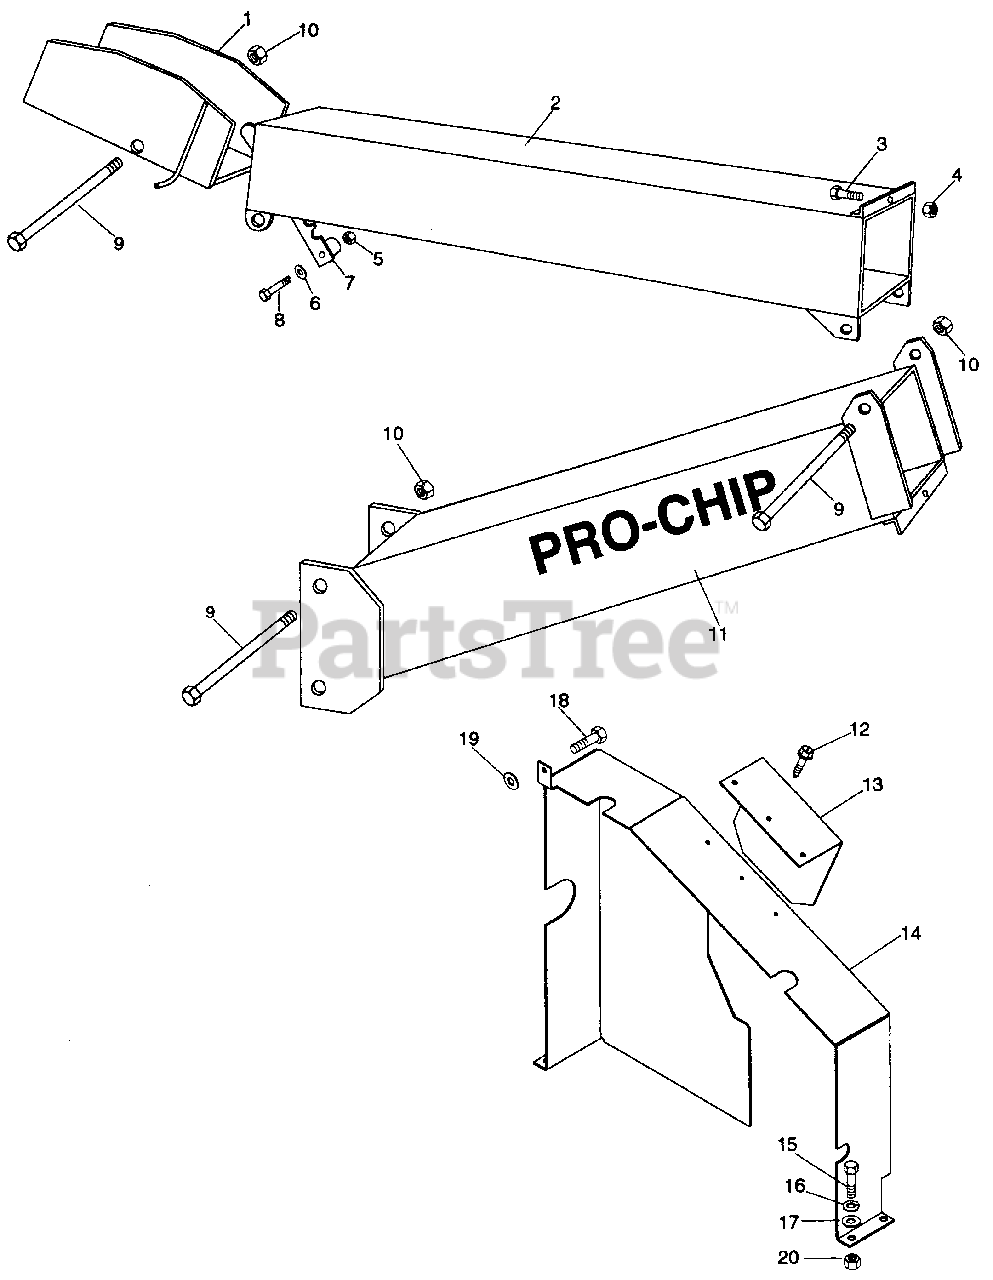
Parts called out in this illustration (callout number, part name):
1	CAP
2	CHUTE UPPER
3	BLT-HEX .31-18X.75 PL GR 5
4	NUT-LK-NYL .312-18 PL
5	NUT-LK TOP .375-16 GR C PL
6	WSHR-FL-STL .438X1.0X.083 PL
7	LOCK BAR
8	BLT-HEX .38-16X2.00 PL GR 5
9	BLT-HEX .38-16X6.00 PL GR 5
10	NUT-LK TOP .375-16 GR C PL
11	LOWER CHUTE
12	SCR-TAP .250-20X.37 HWH PL TR
13	SHEAVE GUARD
14	BELT GUARD WELDMENT
15	BLT-HEX .31-18X1.00 PL GR 5
16	WSHR-LOCK .312 ID HEAVY PL
17	WSHR-FL-STL .38X.875X.083 PL
18	BLT-HEX .25-20X.50 PL GR 5
19	WSHR-LOCK .250X.007 HVY PL
20	NUT-HEX .312 - 18
